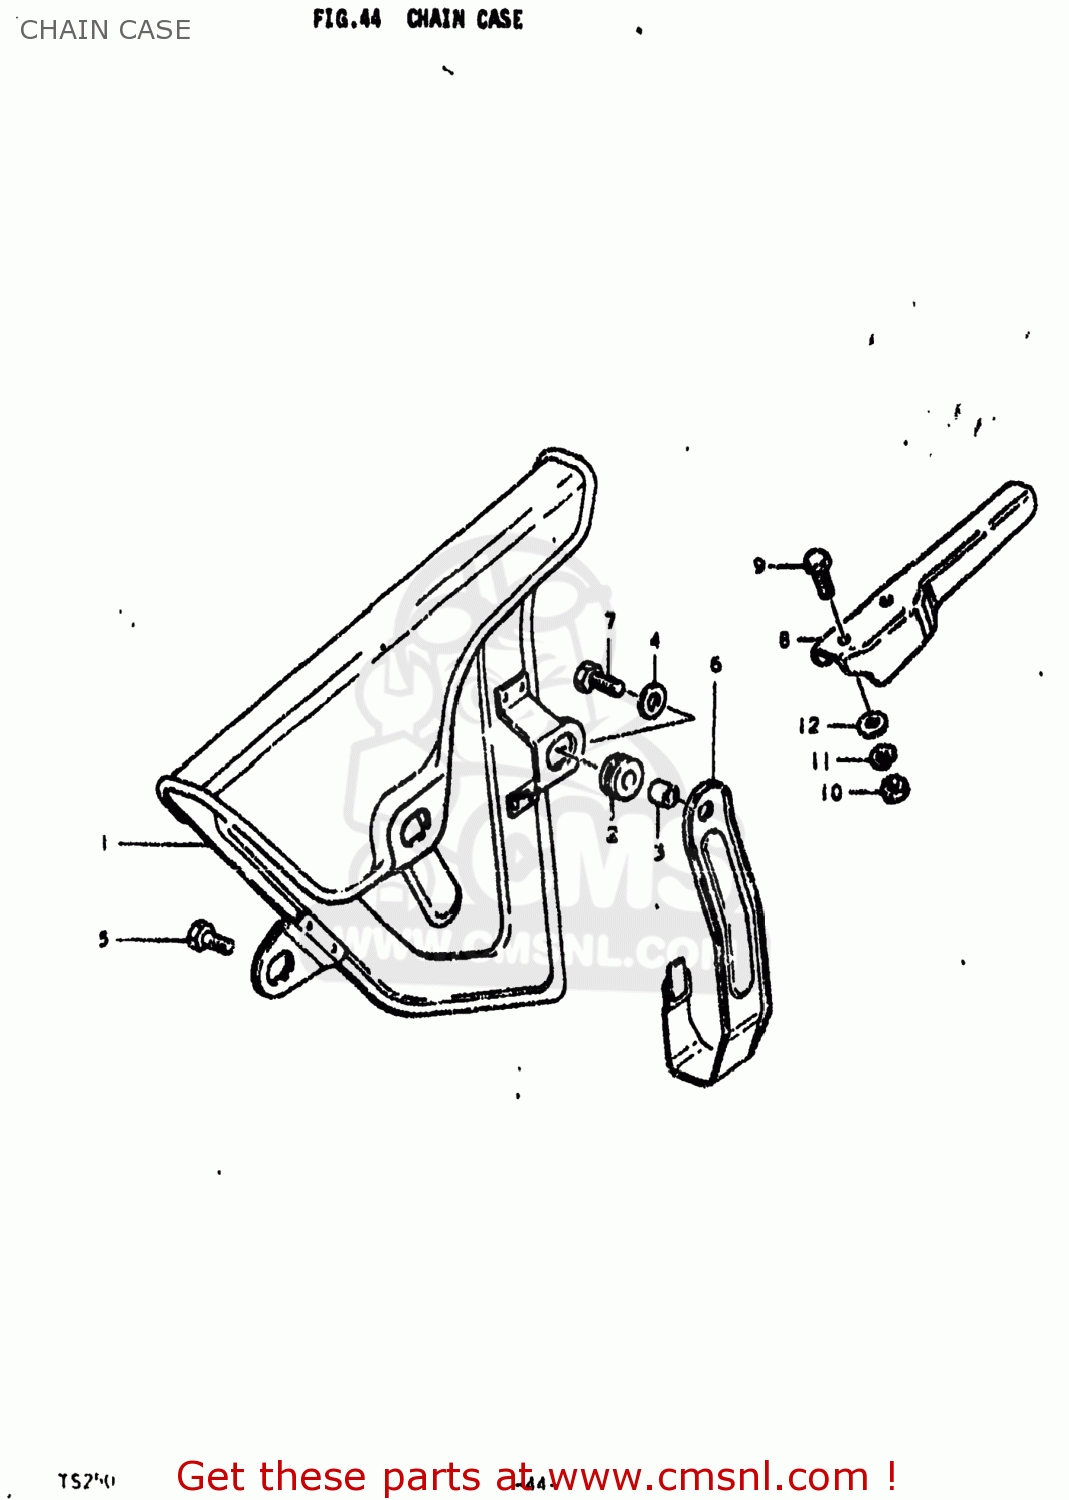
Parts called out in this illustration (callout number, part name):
1	CASE,CHAIN
2	CUSHION
3	SPACER (7X9X7)
4	WASHER (6.5X20X1.2)
5	BOLT
6	GUIDE,DRIVE CHAIN
7	SCREW(6X14)
9	BOLT
10	NUT
11	LOCK WASHER
12	WASHER
